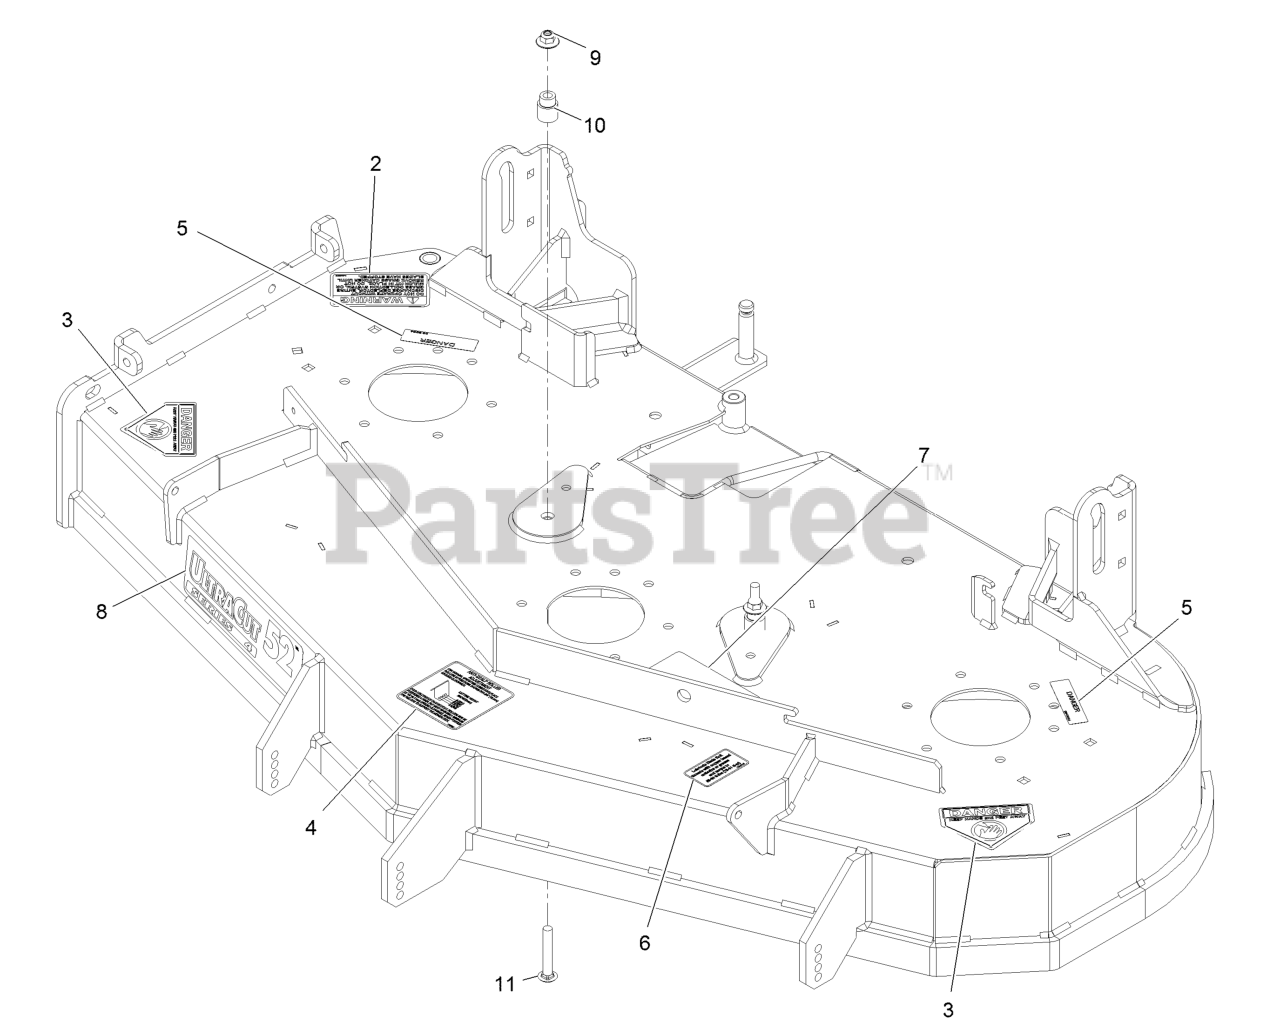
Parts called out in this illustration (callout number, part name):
2	DECAL-WARNING, DISCHARGE
3	DECAL-DANGER
4	DECAL,ANTISCALP
5	DECAL-COVER, MISSING
6	DECAL,BOLT TORQUE
7	DECAL,BELT ROUTING
8	DECAL,ULTRACUT 52 SERIES
9	Nut-Nyloc 3/8-16 Flg
10	BUSHING-IDLER
11	SCREW-CARR
